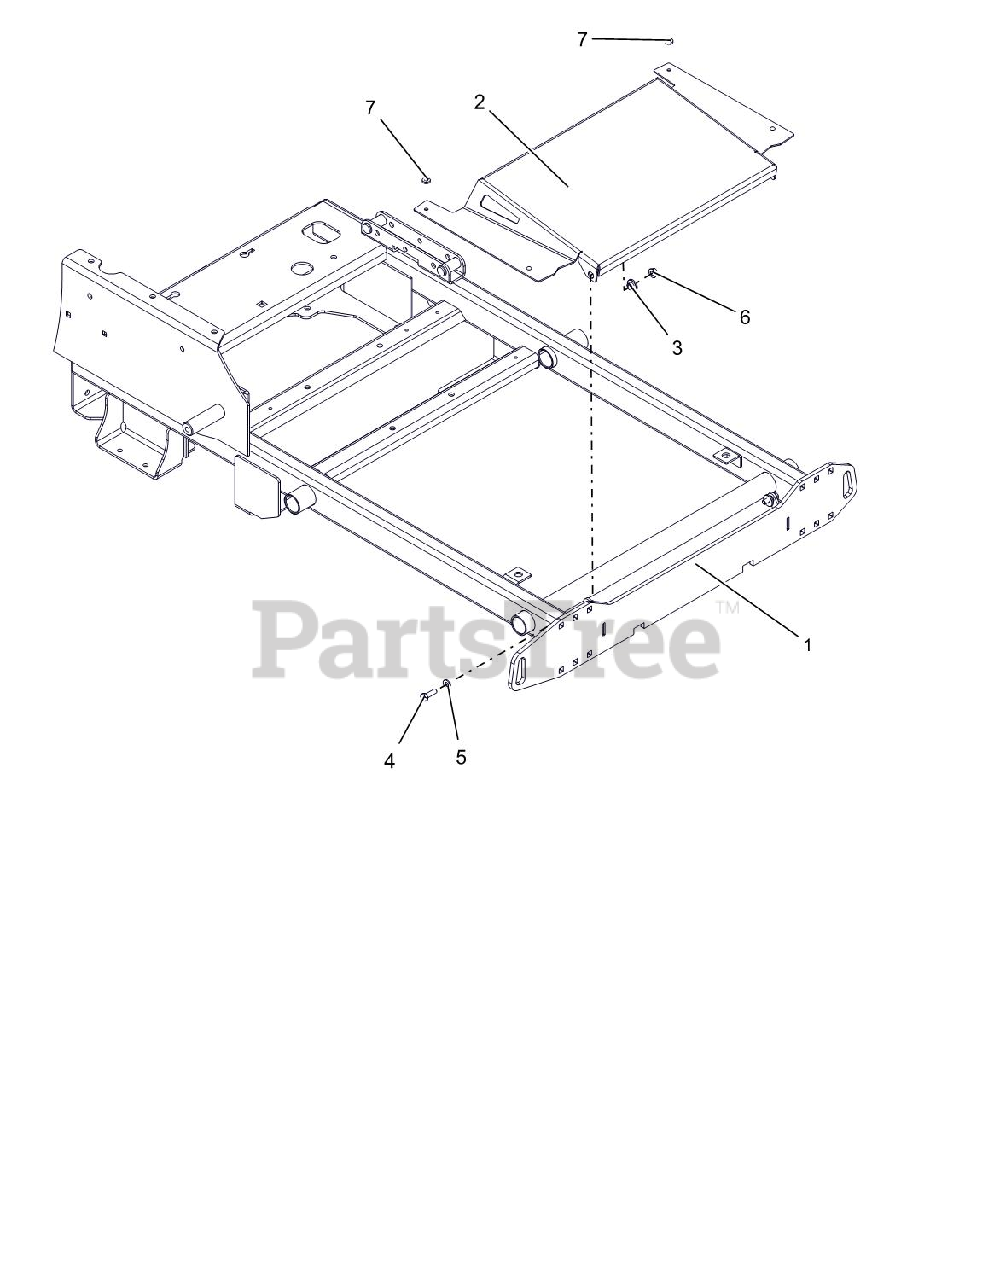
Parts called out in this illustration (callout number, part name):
1	WMT,FRAME,48-52" PRO-STANCE
2	SHEILD, FRONT PRO-STANCE
3	BSHG-FLG .32X.500X.344X.880
4	@BLT-HEX .31-18X1.00 GR5 YWZC
5	@WSHR-FL-STL.344X.688X.065YWZC
6	@NUT-LK-TOP-FLG .31-18 YWZC
7	BUMPER GROMMET
